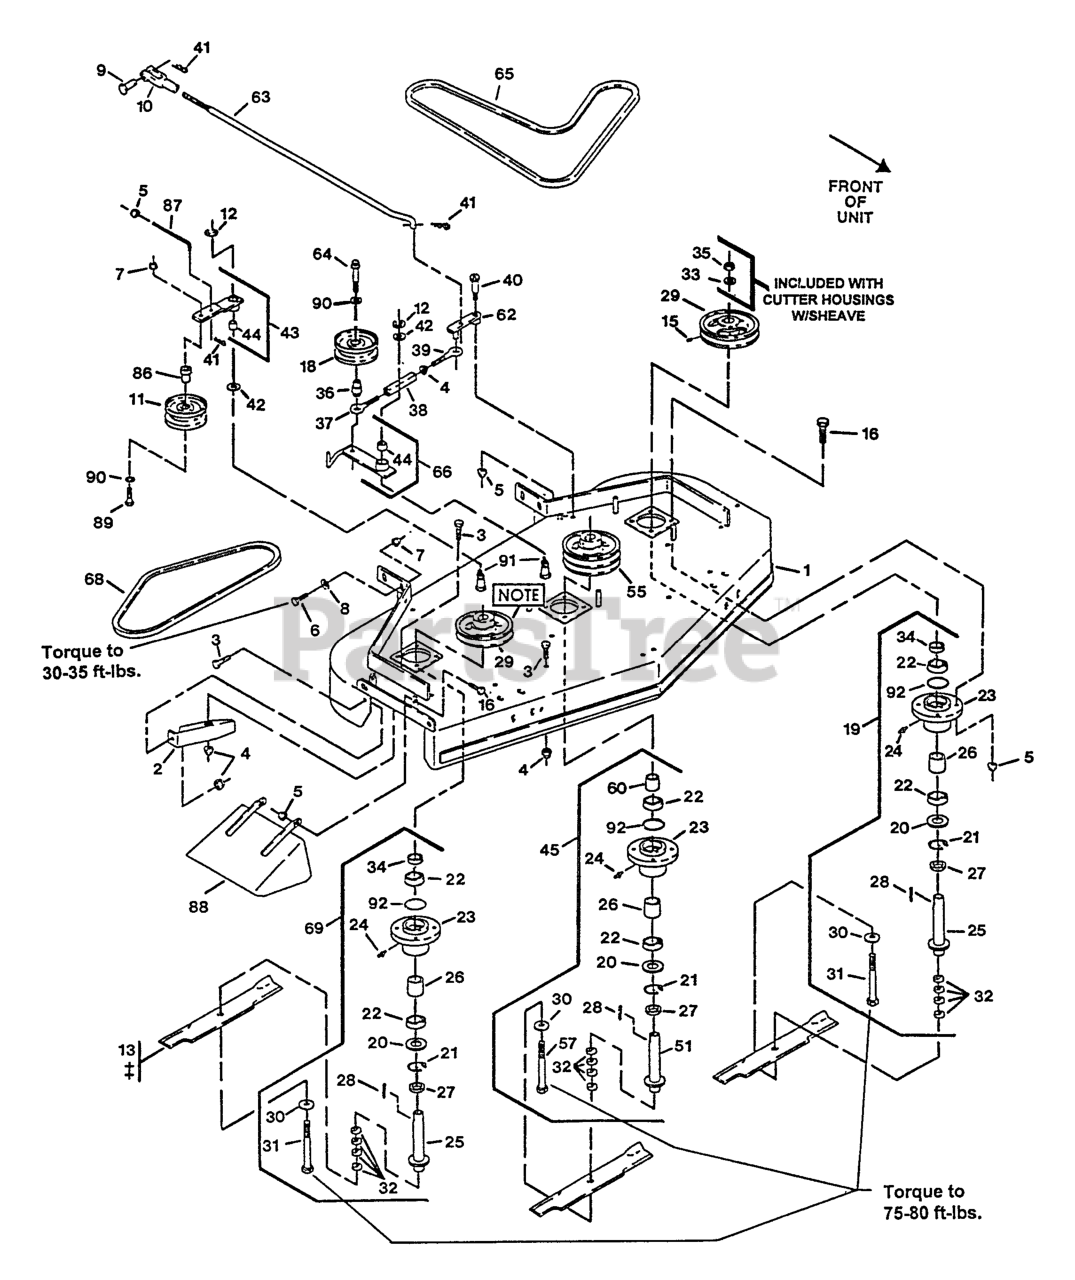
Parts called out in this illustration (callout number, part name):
2	BAFFLE-DOGLEG
9	PIN-CLEVIS
10	YOKE-ADJUSTABLE
11	IDLER,PULLEY
15	SCREW-SET
19	ASM,HOUSING CUTTER
20	SEAL,DUST
21	RING,SNAP WLDS N5000-244
22	BEARING,HD SPINDLE
23	HOUSING,CUTTER
26	SPACER,BRG/BRG
27	SPACER,BEARING &SPINDLE
30	WASHER-SPRING
31	SCREW-CAP, HH
33	WASHER-RETAINER, SHEAVE
36	BUSHING-ENGAGEMENT
37	EYEBOLT-THREAD, LH
38	BODY-TURNBUCKLE
39	EYEBOLT-THREAD, RH
40	BOLT,SHLDR KSKH
41	PIN-COTTER
42	WASHER-SPINDLE
43	ARM WLDMNT W/BUSHING
44	BEARING,POWDERED METAL
57	SCRW,CAP HH 5/8-18X8.5
59	WASHER-RETAINER, SHEAVE
60	SPACER,BEARING/SHEAVE
63	ARM-ASSIST, LINKAGE
65	BELT,BLADE DRIVE
68	BELT,FRONT DECK
83	WASHER-RETAINER, SHEAVE
86	BUSHING-IDLER
87	LINKAGE
88	Chute
